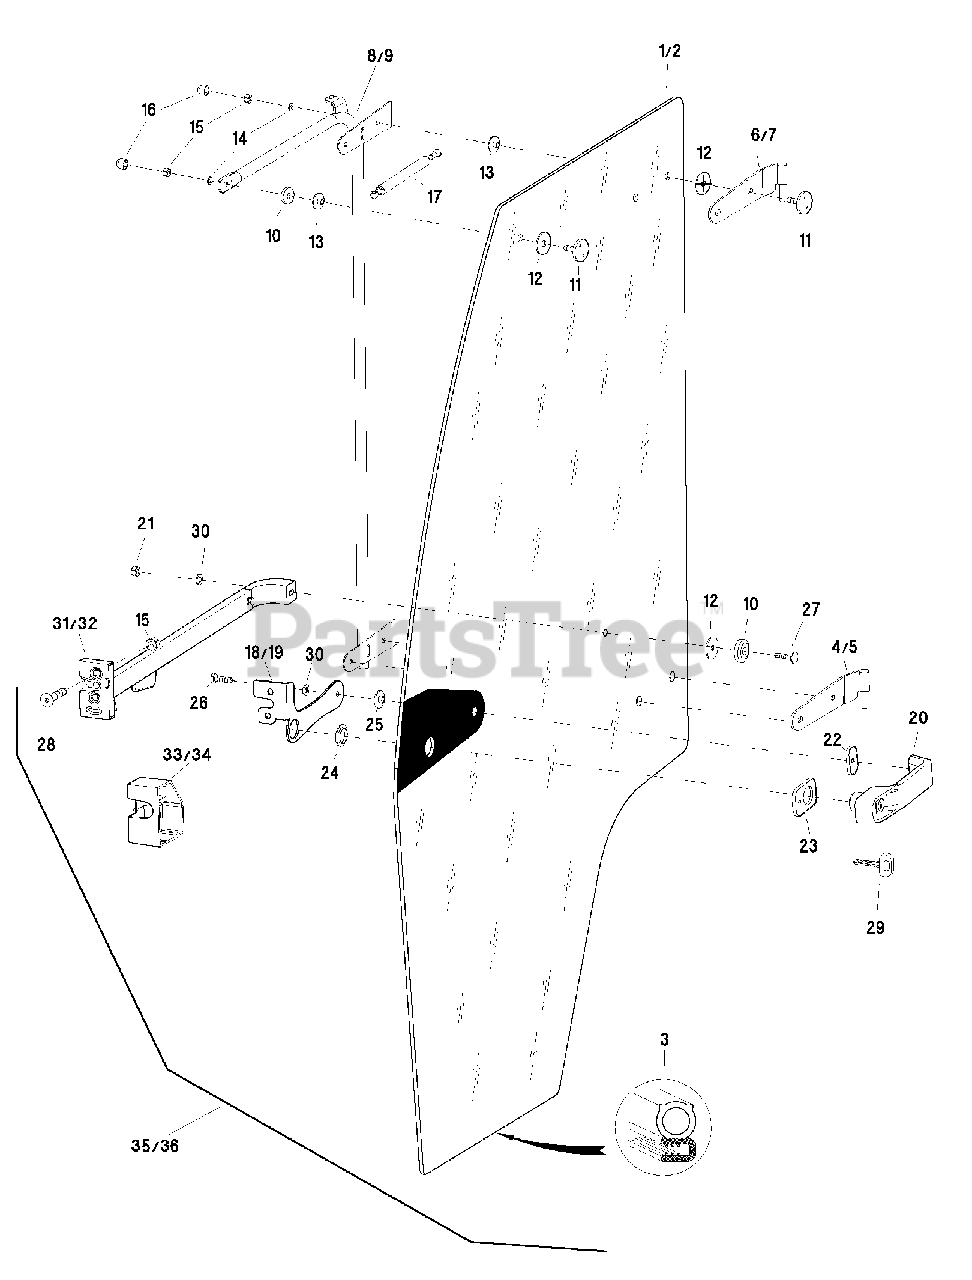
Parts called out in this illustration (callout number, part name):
1	Door window glass left
2	Door window glass right
3	Sealing tube profile
4	Door hingle bottom left
5	Door hinge bottom right
6	Door hinge top left
7	Door hinge top right
8	Door strap left
9	Door strap right
11	PVC - disk with screw M8x30
12	Rubber washer
13	Rubber washer with neck
14	Shim disk M8
15	Stop nut M8
16	Cover cap dm8
17	Pneumatic spring 320mm300N w/end-damp
18	Lock plate for complete glass door left
19	Lock plate for complete glass door right
20	Door handle with lockable latch
21	Stop nut M6
22	Rubber shim medium
23	Rubber shim large
24	Rubber washer with neck large
25	Rubber washer with neck small
30	Shim disk M6
31	Turn-catch lock left with cross arm
32	Turn-catch lock right with cross arm
33	Lock cover left
34	Lock cover right
35	Door left complete (Includes all ref. nos. except ref. nos. 2, 5, 7, 9, 19, 32 & 34)
36	Door right complete (Includes all ref. nos. except ref. nos. 1, 4, 6, 8, 18, 31 & 33)
